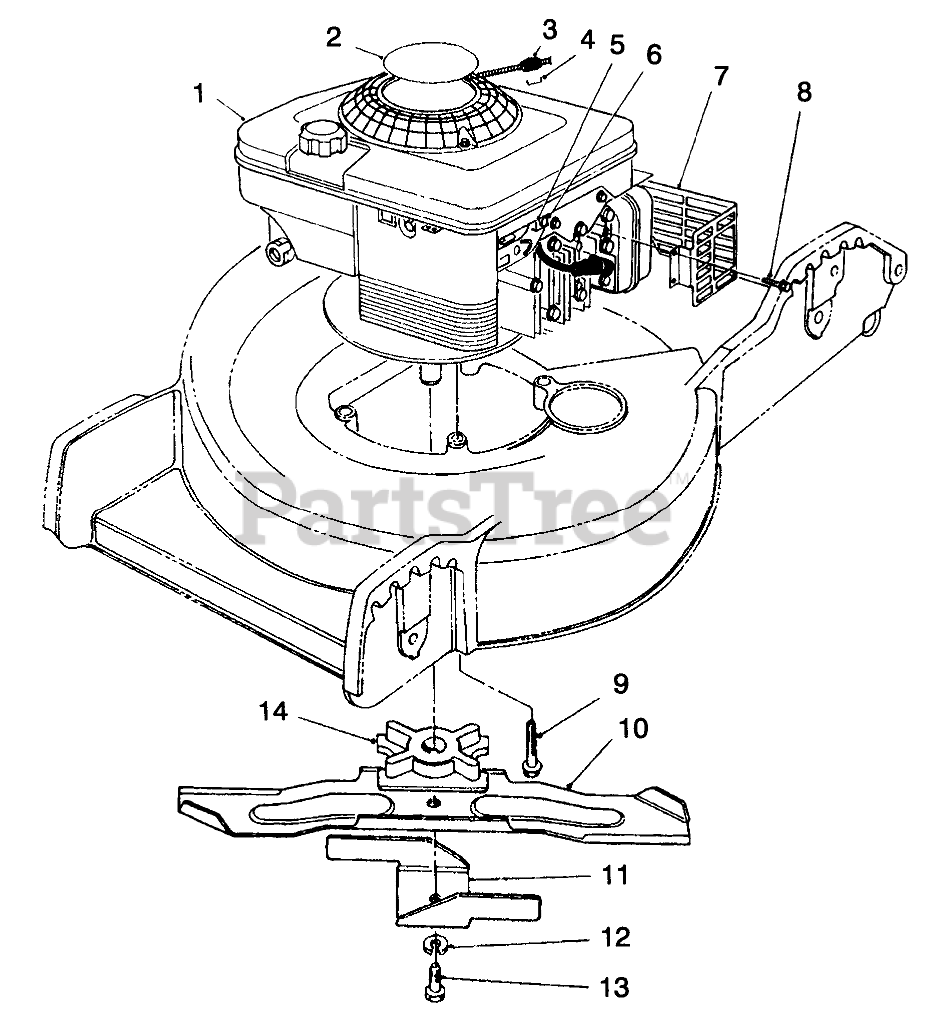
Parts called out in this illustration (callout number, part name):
2	DECAL - ENGINE
3	STOP-ROPE
5	CLAMP-CASING
6	CLAMP SCREW F/W ENGINE
7	SHIELD - MUFFLER
8	SCREW-HWH
9	3/8-16X2 TAPTITE HEX HD
10	Blade-18"
11	18 ACCELERATOR
12	WASHER-LOCK
13	SCREW-HH
14	BLADE RETAINER
